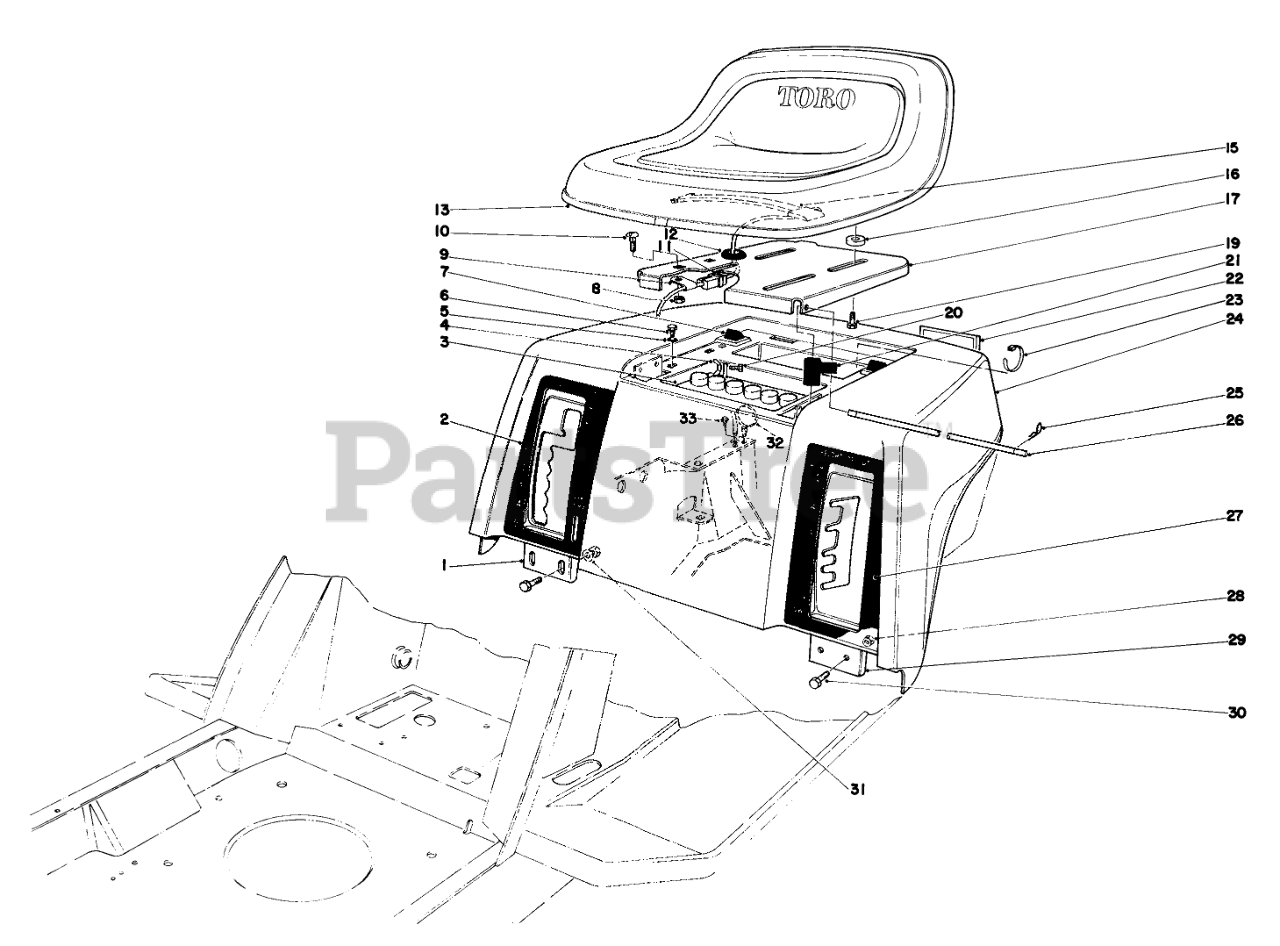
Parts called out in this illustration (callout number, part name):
1	DETENT PLATE B
2	Decal Transmission
3	Battery
4	NUT-WING
5	WASHER
6	SCREW-HWHTF
7	SEAT BUMPER
8	NUT-KEPS
9	CLAMP
10	SCREW-CARR
11	Female Connector
12	GROMMET
15	SWITCH-SEAT
16	SPACER-PIN, MOUNTING
17	SEAT SUPPORT R
19	SCREW-HHF
20	SCREW-HH
21	BOOT-TERMINAL
22	REFLECTOR
24	Rear Body (Incl. Ref. #2 & 27)
25	PIN-COTTER
26	PIVOT-SEAT
27	Decal Height of Cut
28	NUT-LOCK, CONE
29	Quadrant Height of Cut
30	SCREW-HH
31	WASHER-PLAIN
32	TIE-MOUNT, PUSH
33	SCREW-HWHTF
